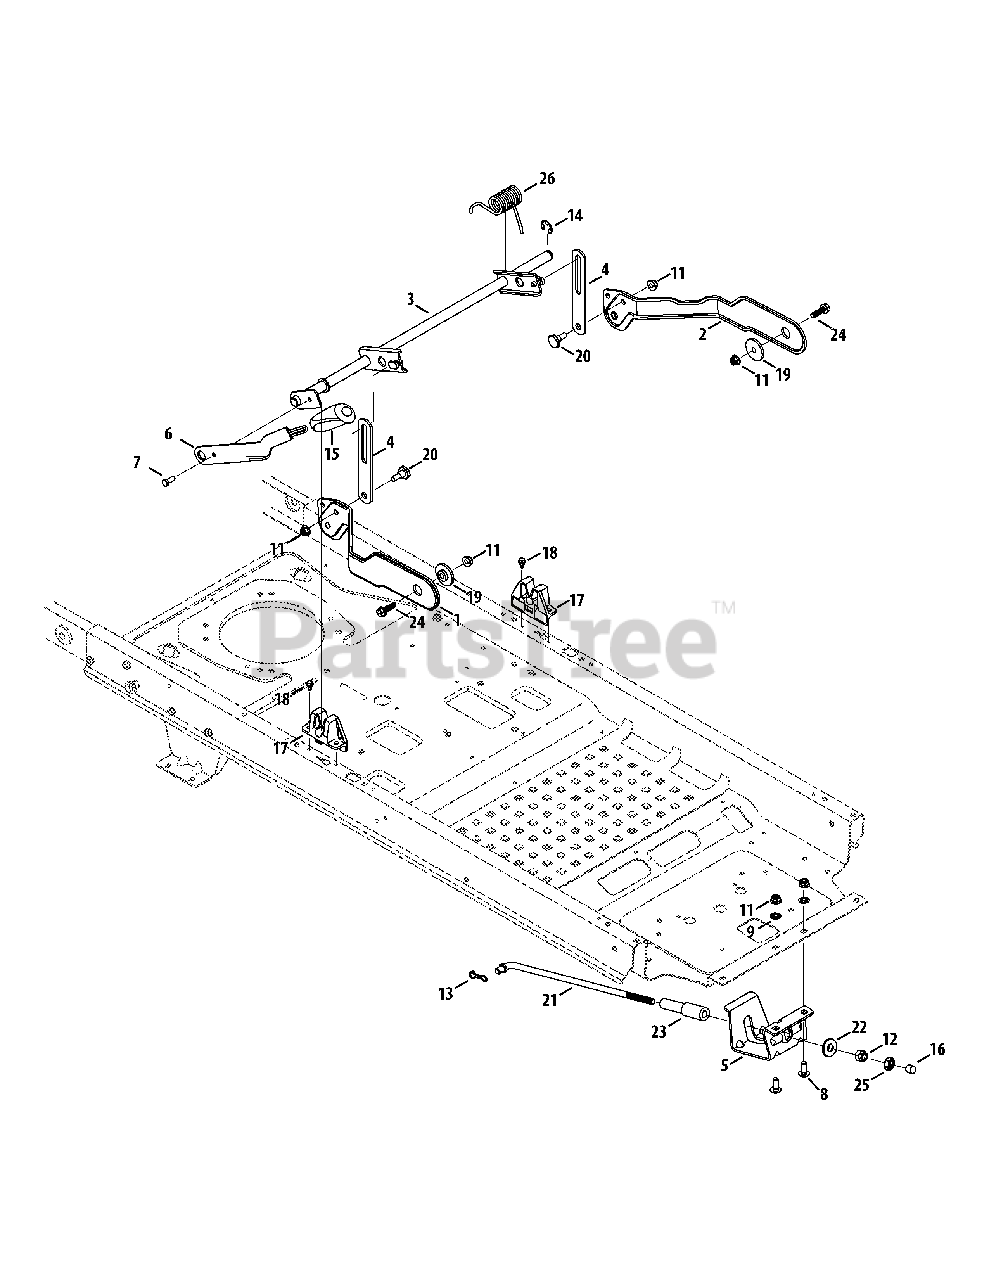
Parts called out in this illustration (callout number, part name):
1	RH Deck Lift Bracket Assembly
2	LH Deck Lift Bracket Assembly
3	Deck Lift Shaft Assembly
4	Lift Link Plate
5	Support Rod Mount Bracket
6	Deck Lift Handle
7	Hex Screw, 5/16-18 x .75
8	Carriage Bolt, 3/8-16 x 1.00
9	Push Nut, 3/8
10	Flange Lock Nut, 5/16-18
11	Flange Lock Nut, 3/8-16
12	Hex Nut, 1/2-13
13	Bow-Tie Cotter Pin
14	E-Ring, .750
16	End Cap
17	Deck Lift Bracket
18	Shoulder Screw, 1/4-20 x .50
19	Anti-Rotate Shoulder Spacer
20	Shoulder Screw, .500 x .434
21	Front Deck Lift Rod
22	Deck Lift Pivot Cup
23	Nylon Sleeve, .55 x 4.50
24	Hex Washer Screw, 3/8-16 x 1.000
25	Jam Nut, 1/2-13
26	Torsion Spring, 1.323 ID x 2.83 LG
